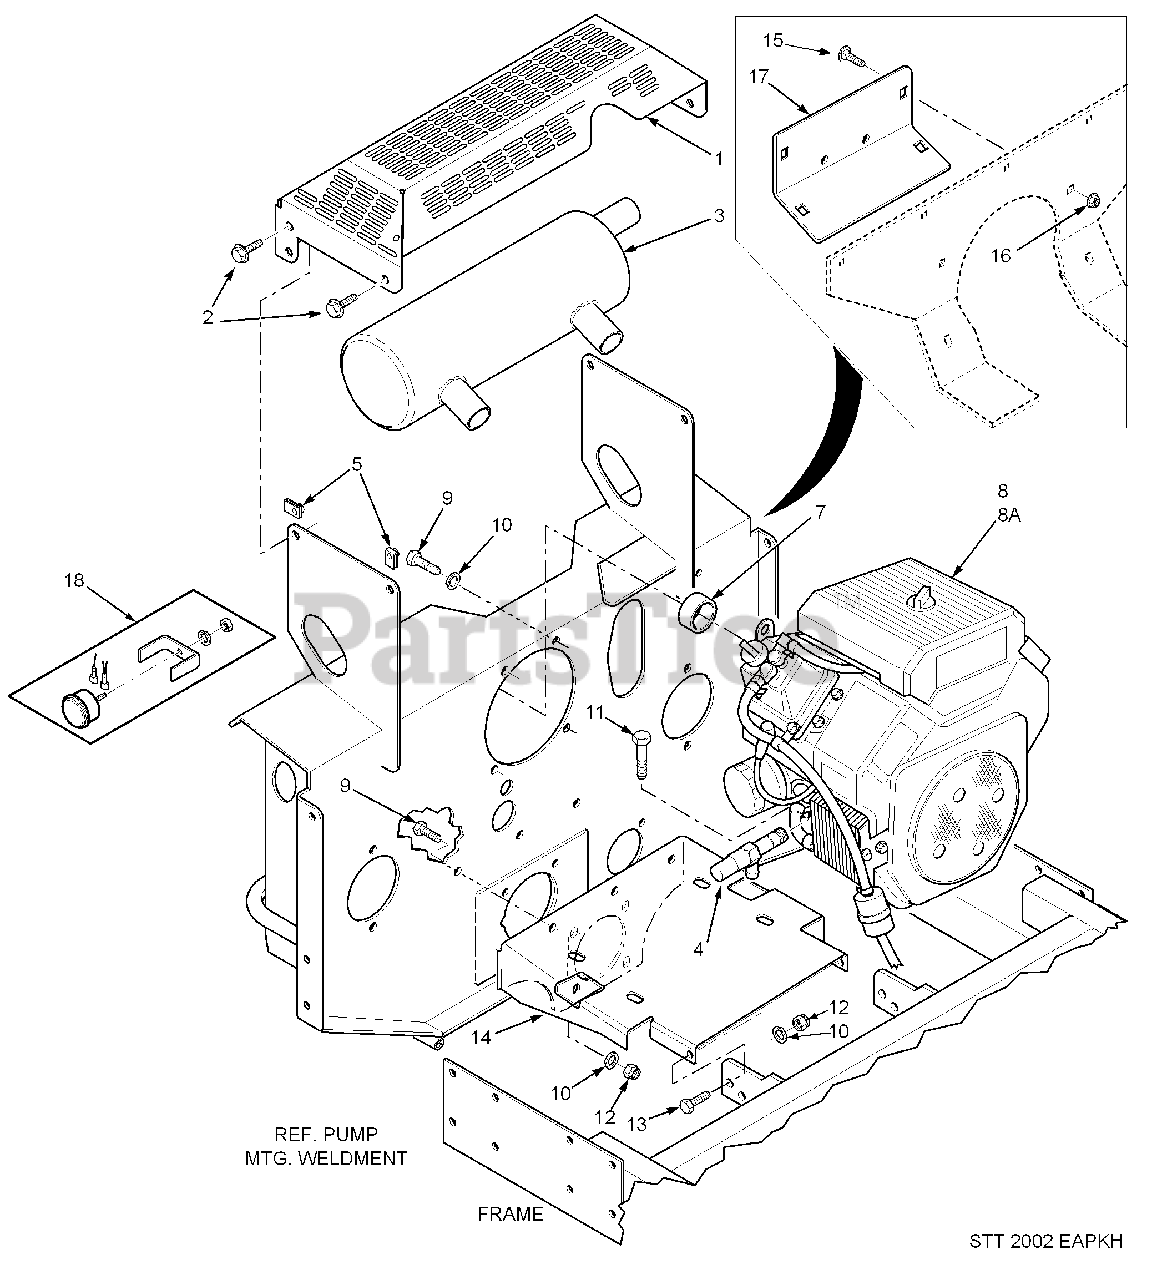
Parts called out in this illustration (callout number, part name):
1	Muffler Guard
2	Screw, Hex Serrated Flange 1/4-20 x 3/4"
3	Muffler, Part Of Engine
4	Oil Drain Extension
5	U-Nut, 1/4-20
6	Exhaust Elbow
7	Spacer, Engine
8	Engine, Kohler 25 CH
9	Bolt, Hex Head 3/8-16 x 1"
10	Lockwasher, 3/8" Spring
11	Bolt, Hex Head 3/8-16 x 1-3/4"
12	Nut, Hex Elastic Stop 3/8-16
13	Bolt, Hex Head 3/8-16 x 1-1/4"
14	Plate, Engine Mounting
15	Bolt, Carriage 5/16-18 x 3/4"
16	Nut, Hex Serrated Flange 5/16-18
17	Rear Cover
18	Hour Meter
